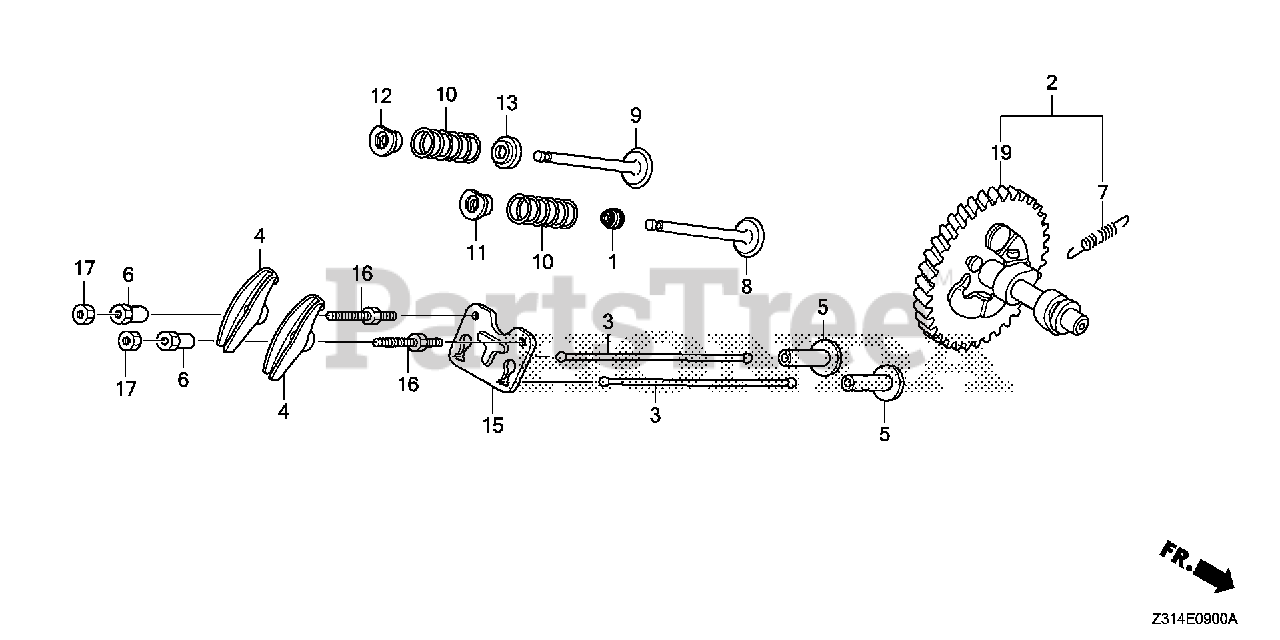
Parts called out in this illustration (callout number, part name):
1	SEAL, VALVE STEM
4	ARM, VALVE ROCKER
5	LIFTER, VALVE
6	PIVOT, ROCKER ARM
8	VALVE, IN.
9	VALVE, EX.
10	SPRING, VALVE
11	RETAINER, IN. VALVE SPRING
12	RETAINER, IN. VALVE SPRING (EXHAUST SIDE)
13	SEAT, VALVE SPRING
15	GUIDE, PUSH ROD
16	BOLT, PIVOT (8MM)
17	NUT, PIVOT ADJUSTING
19	CAMSHAFT (STD)
